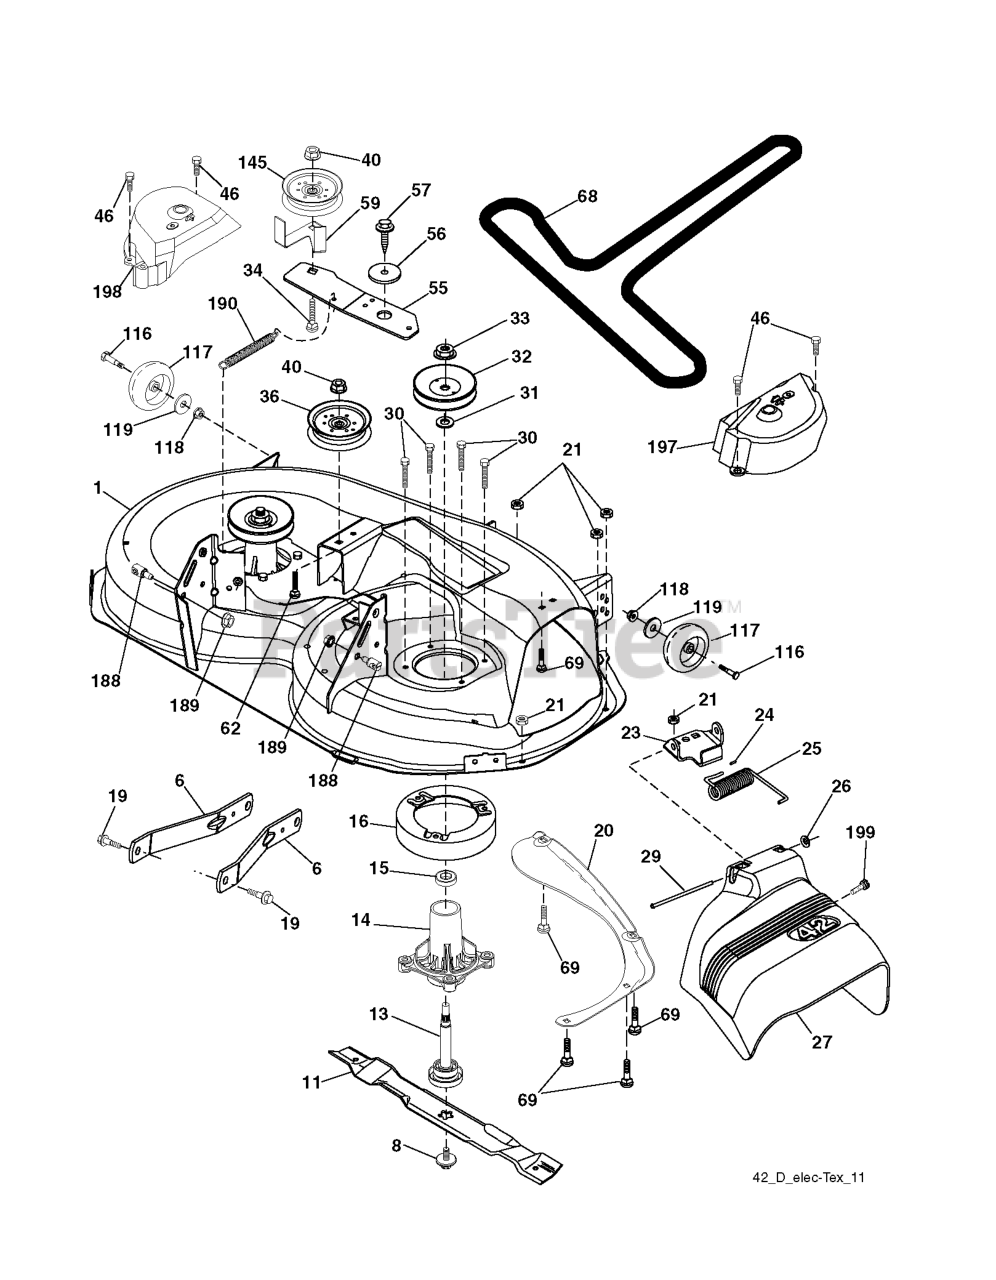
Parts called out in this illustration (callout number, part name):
1	DECK.WELDMENT.42"
6	ARM.SUSPENSION.MOWER.R
8	BOLT.WASHER.ASM.7/16-2
11	42" HI-LIFT BLADE
13	SHAFT.ASM.MDRL.N/GREASE.38
14	RP.HOUSING.MANDREL.4PT.
16	STRIPPER.MANDREL.ROUND.BLACK
19	BOLT.SHOULDER
20	BAFFLE.VORTEX
21	LOCKNUT
23	BRKT.DEFLECTOR.38"2005+
24	CAP-SLEEVE LT
25	SPRING.TORSION.DEFLECT
26	NUT PUSH M
27	DEFLECTOR ASM.42"TEX.FRENCH
29	ROD.HINGE
30	SCREW, WASHER HEAD
31	WASHER.SPACER.MANDREL
32	PULLEY/MANDREL
33	NUT.FLANGE.LOCK.TOP
34	BOLT.3/8-16X1.50
36	PULLEY.IDLER.2006
40	NUT LOCK FLG 3/8-16 UNC
46	SCREW.1/4-20X5/8
56	SPACER.RETAINER
57	SCREW 3/8-16X1
59	GUARD, BELT
68	BELT V SECONDARY
69	BOLT
116	BOLT M
117	WHEEL.GAGE.HALF.SPOKED
118	LOCKNUT
119	WASHER.5/16.FLAT.STE.STD.
145	PULLEY.IDLER.48"PRIMARY
188	STUD.FASTNER.W/ANTI-ROTATE
189	NUT LOCK HEX FLANGE 5/16-18
190	SPRING.MOWER.DRIVE.ELECTRIC
199	SCREW 3/8-16X1/2
